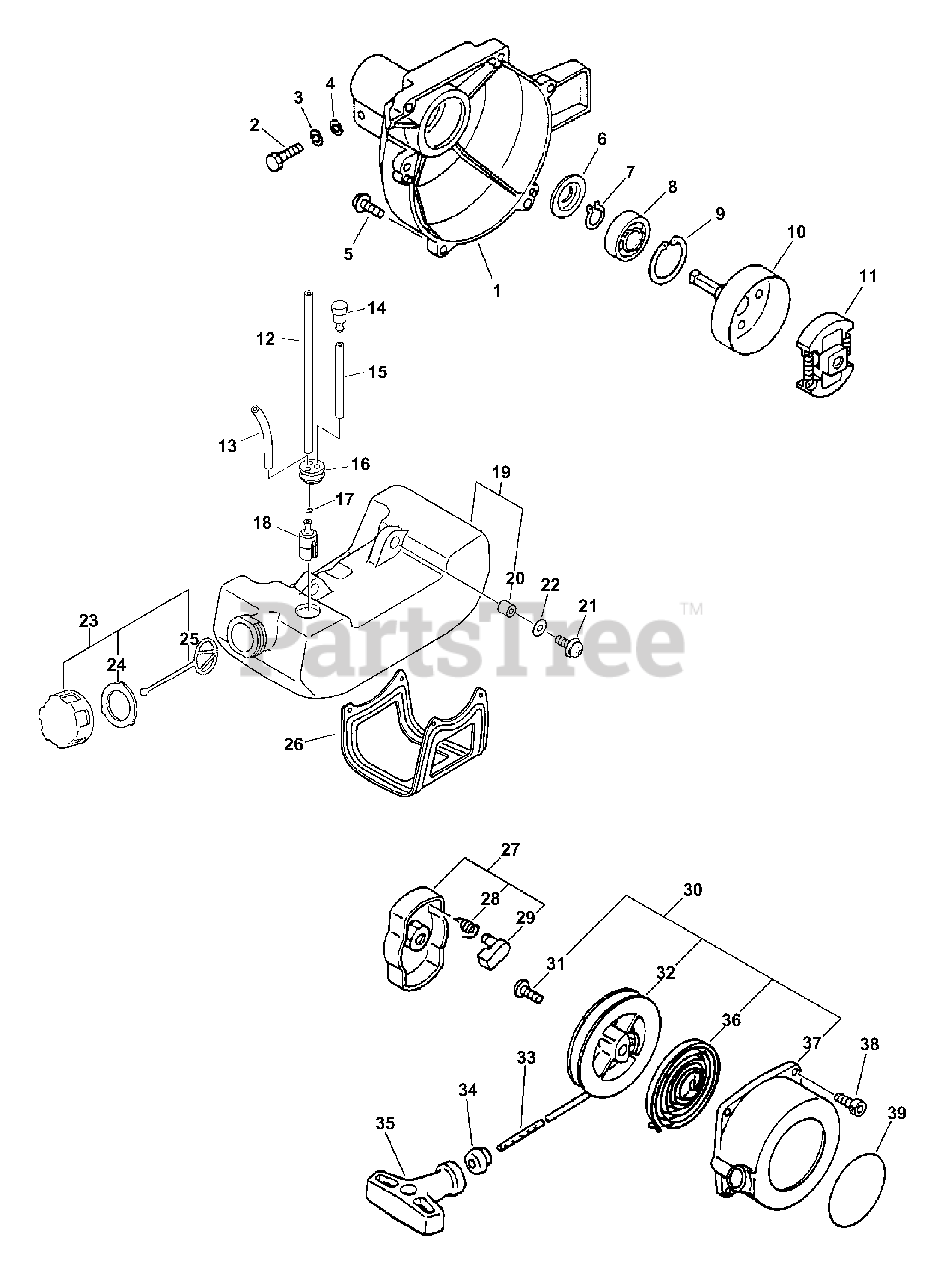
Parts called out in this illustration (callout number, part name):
1	CASE, FAN - ORANGE
2	BOLT - 5X25
3	LOCKWASHER - 5
4	WASHER - 5
5	SCREW - 4X16
6	RETAINER, PIPE
7	RING, RETAINING - 12
8	BEARING, BALL - 6201
9	RING, RETAINING - 32
10	DRUM, CLUTCH
11	CLUTCH ASSY
12	PIPE - 3X5X180 -- BLACK
13	PIPE - 3X6X90 -- CLEAR
14	VENT, FUEL TANK
15	PIPE - 3X5X70 -- BLACK
16	GROMMET
17	CLIP - 6
18	FILTER, FUEL
19	FUEL TANK ASSY
21	SCREW - 5X16
22	WASHER - 5
23	CAP ASSY
24	GASKET, CAP
25	CONNECTOR, CAP
26	GUARD, FUEL TANK
27	STARTER PAWL ASSY
28	SPRING, RETURN
29	PAWL, STARTER - BLACK
30	STARTER ASSY
32	REEL, ROPE
33	ROPE, STARTER - 3X1000
34	GUIDE, ROPE
35	GRIP, STARTER
36	SPRING, REWIND
37	CASE, STARTER
38	SCREW - 4X16
39	LABEL - ECHO
